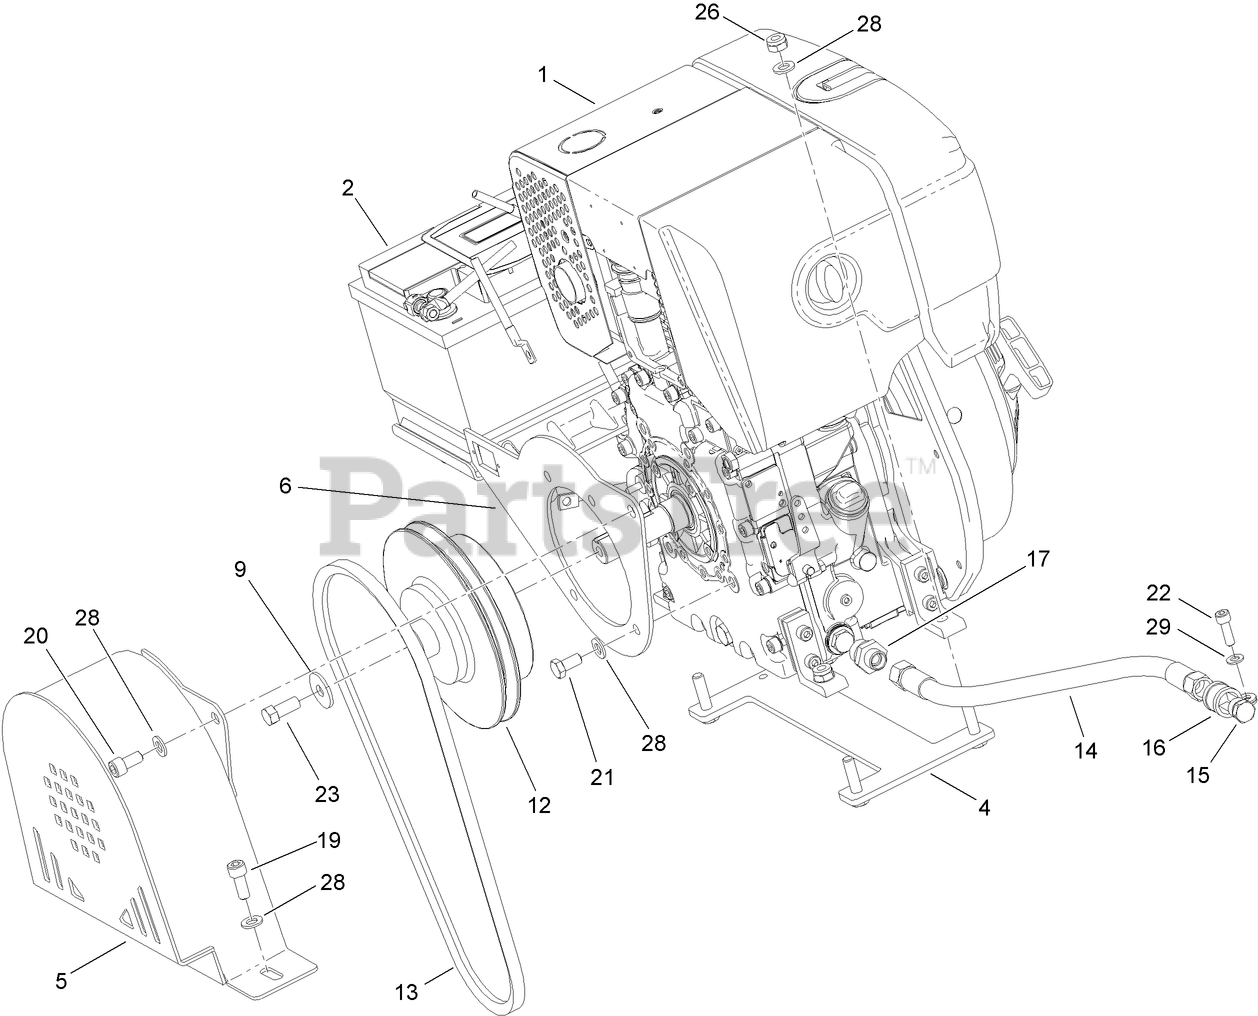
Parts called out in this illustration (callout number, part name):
1	ENGINE ASM
2	BATTERY CARRIER ASM
4	CONTROL-ENGINE
5	COVER-PULLEY
6	HOLDER-COVER
9	WASHER
12	COUPLING
13	V-BELT
16	CLIP-HOSE
17	SOCKET-STRAIGHT
21	SCREW-HH
28	WASHER
29	WASHER
